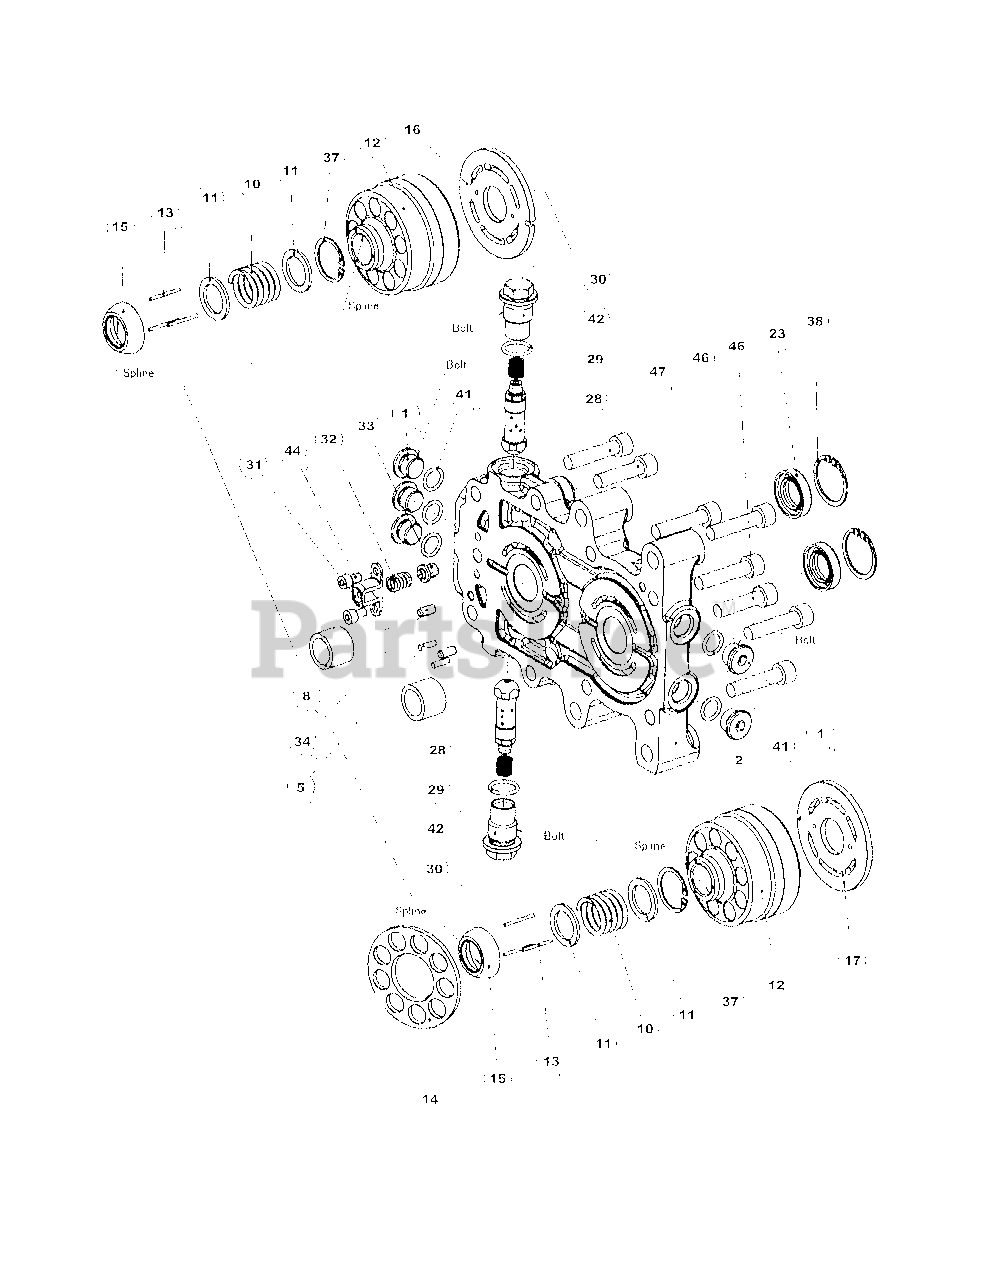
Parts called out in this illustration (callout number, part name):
1	Plug PF3/8
2	Center section
3	Housing
4	Housing packing
5	Pin 4 x 14
6	Input shaft
7	Shaft
8	Needle bearing
9	Plunger assembly
10	Plunger spring
11	Spring retainer
12	Plunger block
13	Pin
14	Retainer
15	Retainer washer
20	Cover
21	Cover
22	Bush
23	Seal 20 x 35 x 8
24	Seal 25 x 45 x 8
27	O-ring S58.2
28	Neutral and Check Relief (NCR) valve + 0.7
29	Spring (Check valve)
30	Plug
31	Retainer
32	Valve spring
33	Valve assembly
36	Ring 25
37	Ring 32
40	Bearing 6305 C3NTN
41	Packing P 14.0
42	Packing P 18.0
43	Packing G 65.0
44	Bolt 6 x 10
48	Screw 6 x 12
